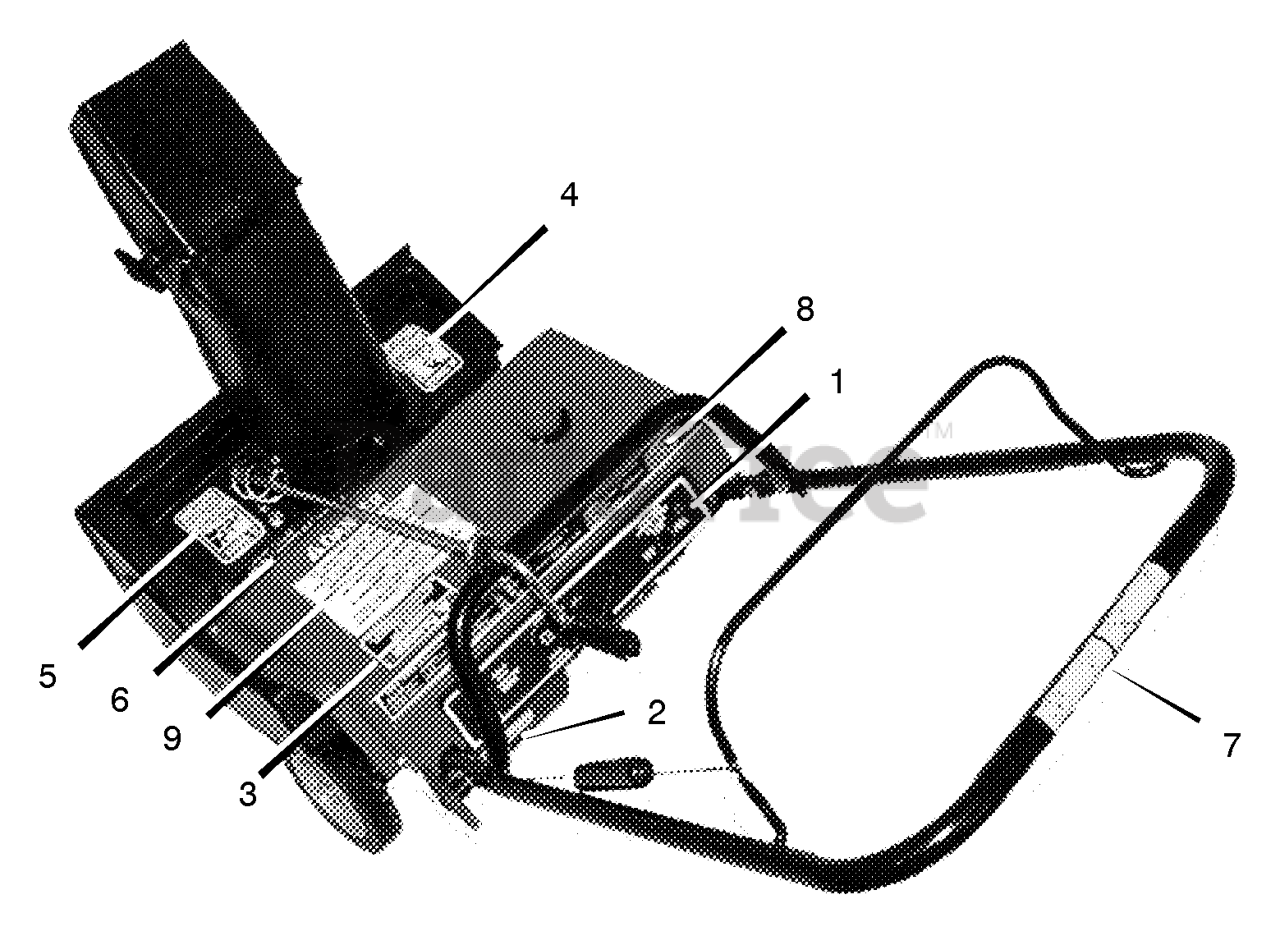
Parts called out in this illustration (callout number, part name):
1	DECAL, CONTROL PANEL
2	DECAL, CHOKE
3	DECAL, HOT MUFFLER
4	DECAL, CHUTE DANGER
5	DECAL, AUGER DANGER
6	DECAL, MURRAY 3.5/20
7	DECAL, AUGER CONTROL BAR
8	DECAL, START INSTRUCTIONS
9	DECAL, DANGER READ
